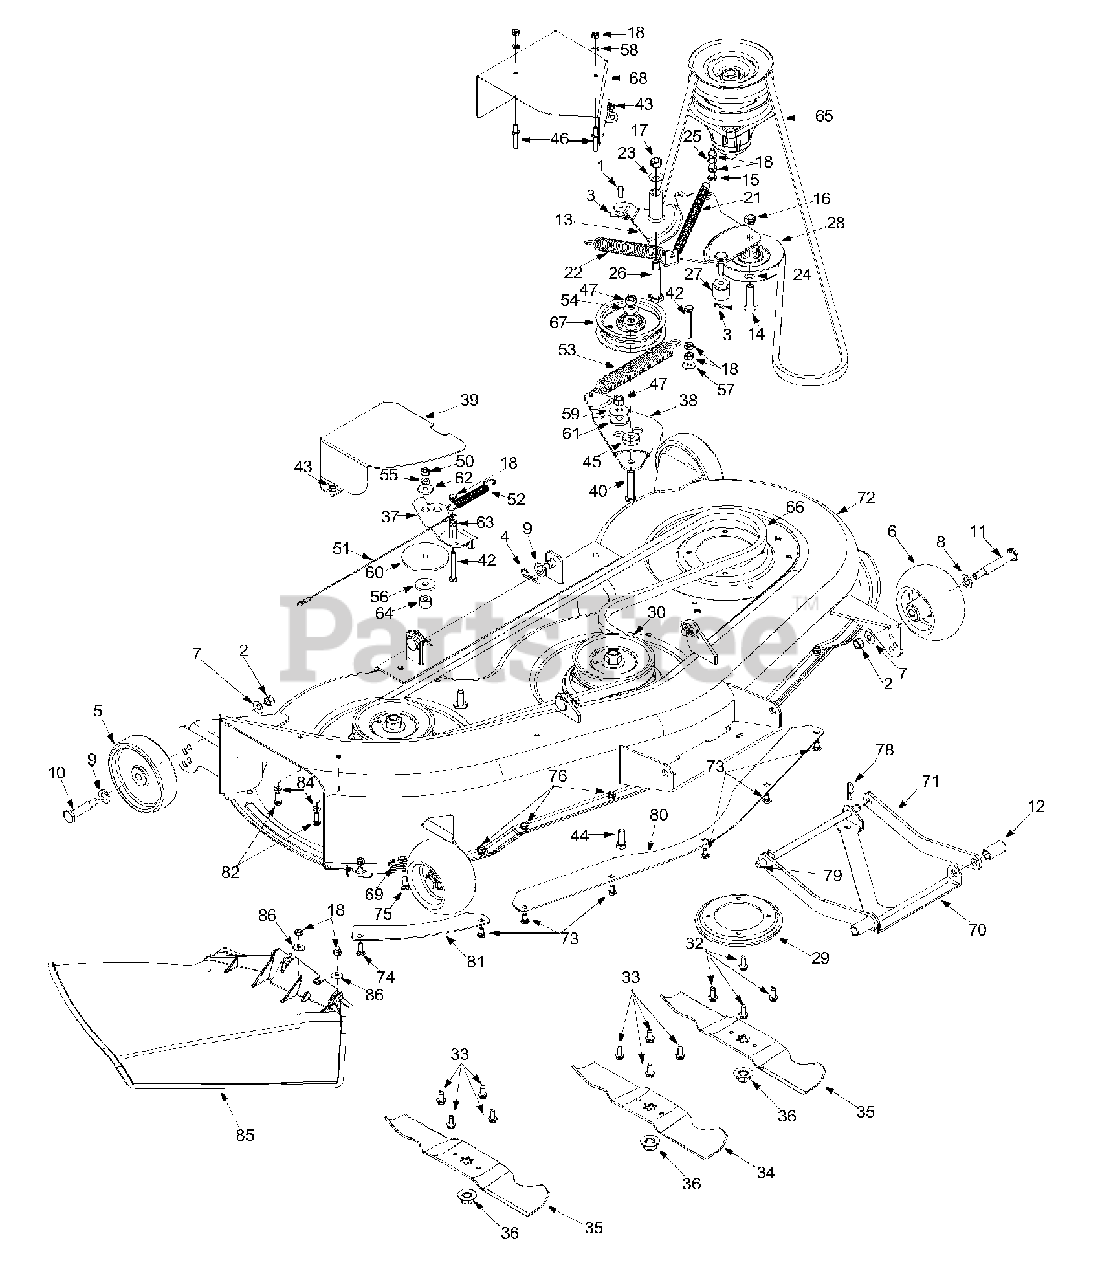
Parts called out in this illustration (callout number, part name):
1	Clevis Pin
2	Hex Nut 3/8-16
3	Hairpin Clip
4	Click Pin
5	Deck Wheel
6	Deck Wheel
7	Spring Washer
8	Flat Washer
9	Flat Washer
10	Shoulder Screw
11	Shoulder Screw
12	Spacer
13	Idler Bracket Assembly
14	Hex Screw: Special 3/8-24 x 1.50"
15	Hex Screw 1/4-20 x 2.0"
16	Lock Nut 3/8-24
17	Lock Nut 3/8-16
18	Hex Nut 1/4-20
21	Extension Spring
22	Extension Spring
23	Bell Washer
24	Flat Washer
25	Lock Washer
26	Shoulder Bolt
27	Spacer
28	Idler Pulley
32	TT Screw 5/16-18 x 0.875"
33	LD SCrew 5/16-18 x 0.75"
34	Blade: 14.88" Star Two in-one
35	Blade: 16.28" Star Two in-one
36	Flange Nut 5/8-18
37	Brake Assembly
40	Hex Screw 3/8-24 x 2.0"
42	Hex Screw 1/4-20 x 2.0"
43	TT Screw 1/4 - 20 x 0.5"
44	Hex Screw 3/8 - 24 x 1.0"
45	Spacer
46	Belt Guard Pin
47	Hex Nut 3/8 - 24
50	Hex Nut 5/16 - 24
51	Brake Cable
52	Extension Spring
53	Extension Spring
54	Bell Washer
55	Lock Washer
56	Flat Washer
57	Bell Washer
58	Lock Washer
59	Bell Washer
60	Flat Washer
61	Spacer
62	Spacer
63	Spacer
64	Spacer
65	V-Belt
66	V-Belt
67	Idler Pulley
69	Retainer Bracket
73	Carriage Screw 1/4-20 x 0.50"
74	Carriage Screw 1/4 - 20 x 0.75"
75	Hex Screw 1/4-20 x 0.620"
76	Sems Nut
78	Hairpin Clip
79	Connecting Rod
82	Hex Screw 1/4 - 20 0.620"
84	Push Nut
85	Side-Discharge Chute
86	Bell Washer
